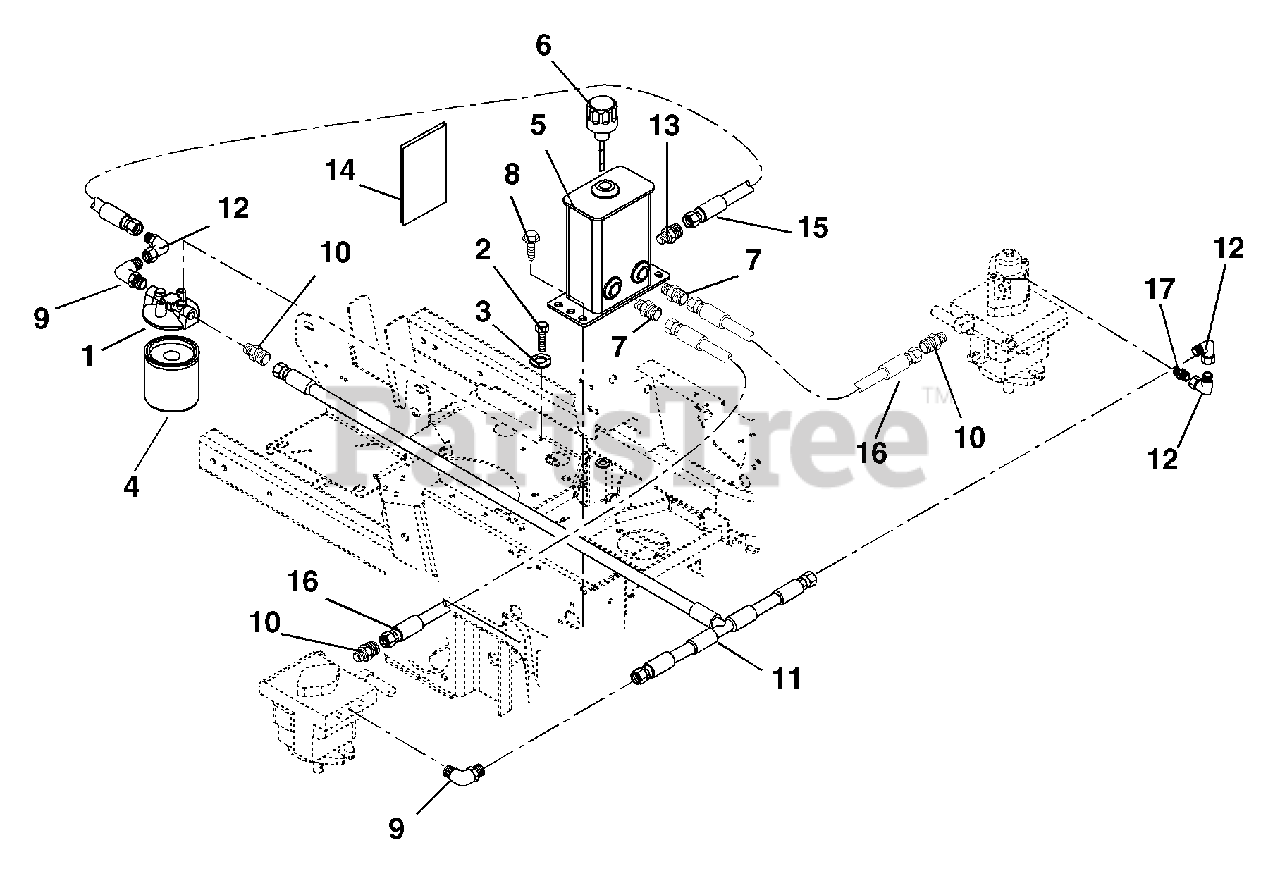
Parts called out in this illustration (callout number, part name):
1	HEAD, FILTER
2	@BLT-HEX .25-20X.50 GR5 YWZC
3	@WSHR-LK .25X.062 REG YWZC
4	ELEMENT, FILTER BE-40-0
5	WMT, HYDRAULIC TANK
6	BREATHER, DIPSTICK
7	ADPT - STRAIGHT 6-8F50X
8	@SCR-TAP .38-16X.50 HWH TR YWZ
9	ADPT 2503-6-6
10	ADPT-PIPE (0503-6-6)
11	HOSE, TEE ASSEMBLY 3/8"
12	ADPT 3903-6-6
13	FTG HYD 45DEG M6J-M8O
14	SHEILD, HEAT 5.50X4.50
15	HOSE, HYD .38-9-0K F6J0-F6J0
16	HOSE, HYD .38-3-0K F6J0-F6J9
17	ADP 0503-4-6
